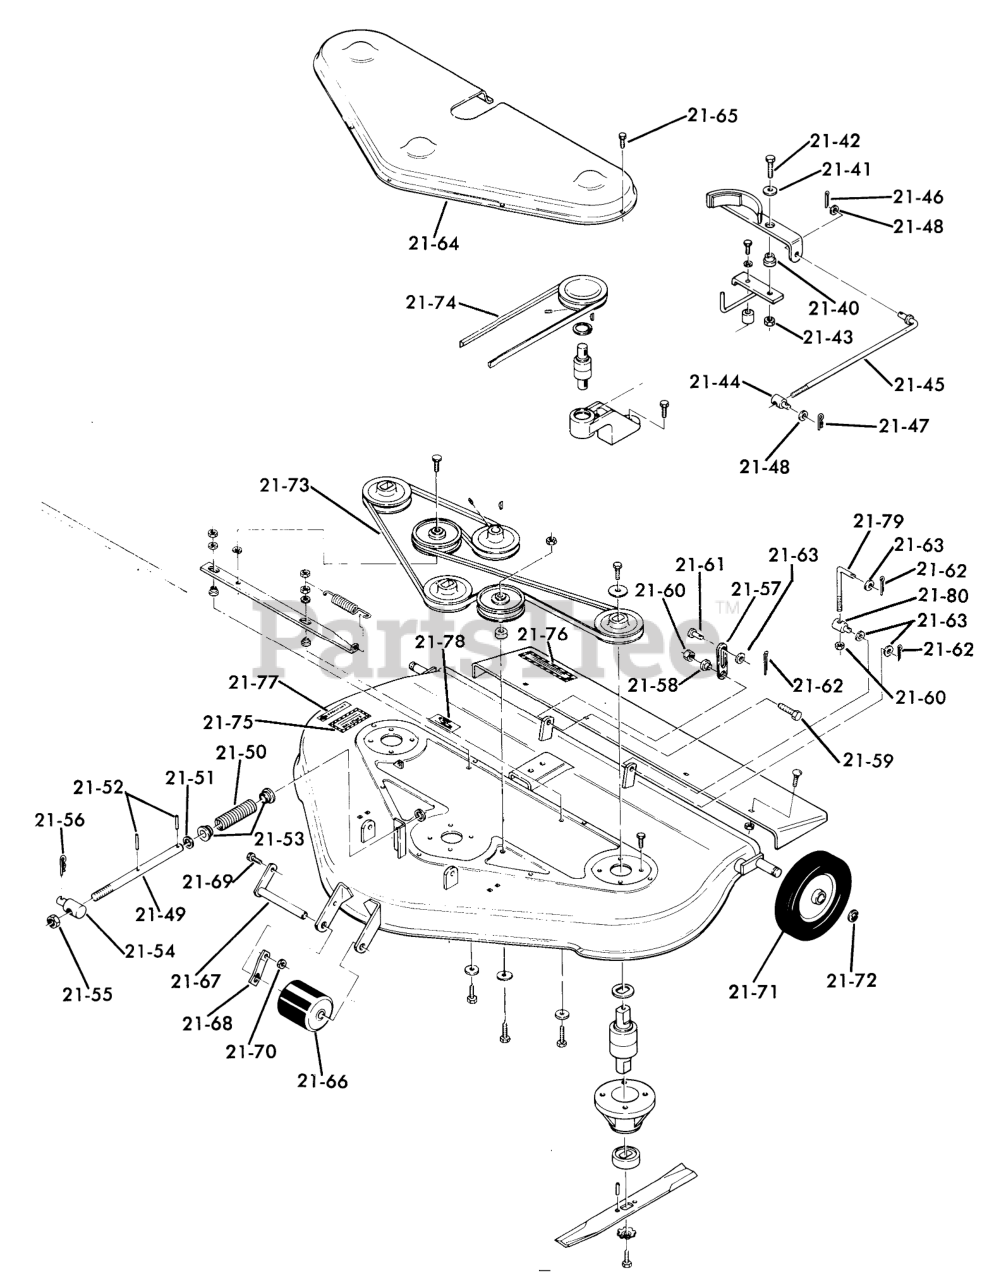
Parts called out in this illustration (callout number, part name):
21-40	SPACER
21-41	WASHER
21-42	BOLT
21-43	Nut
21-44	TRUNNION
21-46	Cotter Pin
21-47	Hairpin Cotter
21-48	Washer
21-49	Link Rod
21-50	SPRING
21-51	WASHER
21-52	SPIROL PIN
21-53	BUSHING
21-54	Trunnion
21-55	Hex Nut 7/16-14
21-56	Hairpin Cotter
21-57	BAR-LIFT LINK R
21-58	SPACER-LIFT LINK
21-59	Bolt
21-60	Nut
21-61	CLEVIS PIN
21-62	Cotter Pin
21-63	Washer
21-64	Belt Cover
21-65	Bolt
21-66	Roller
21-67	Roller Shaft
21-68	SPRING ROLLER STOP
21-69	H H C S
21-70	Nut
21-71	Wheel
21-72	E Ring
21-73	80" Mower Belt
21-74	BELT-40IN DRIVE
21-75	Caution Decal
21-76	Guard Decal
21-77	Decal-Edge of Cut
21-78	Belt Installation Decal
21-79	ROD-LIFT
21-80	STUD-LIFT
